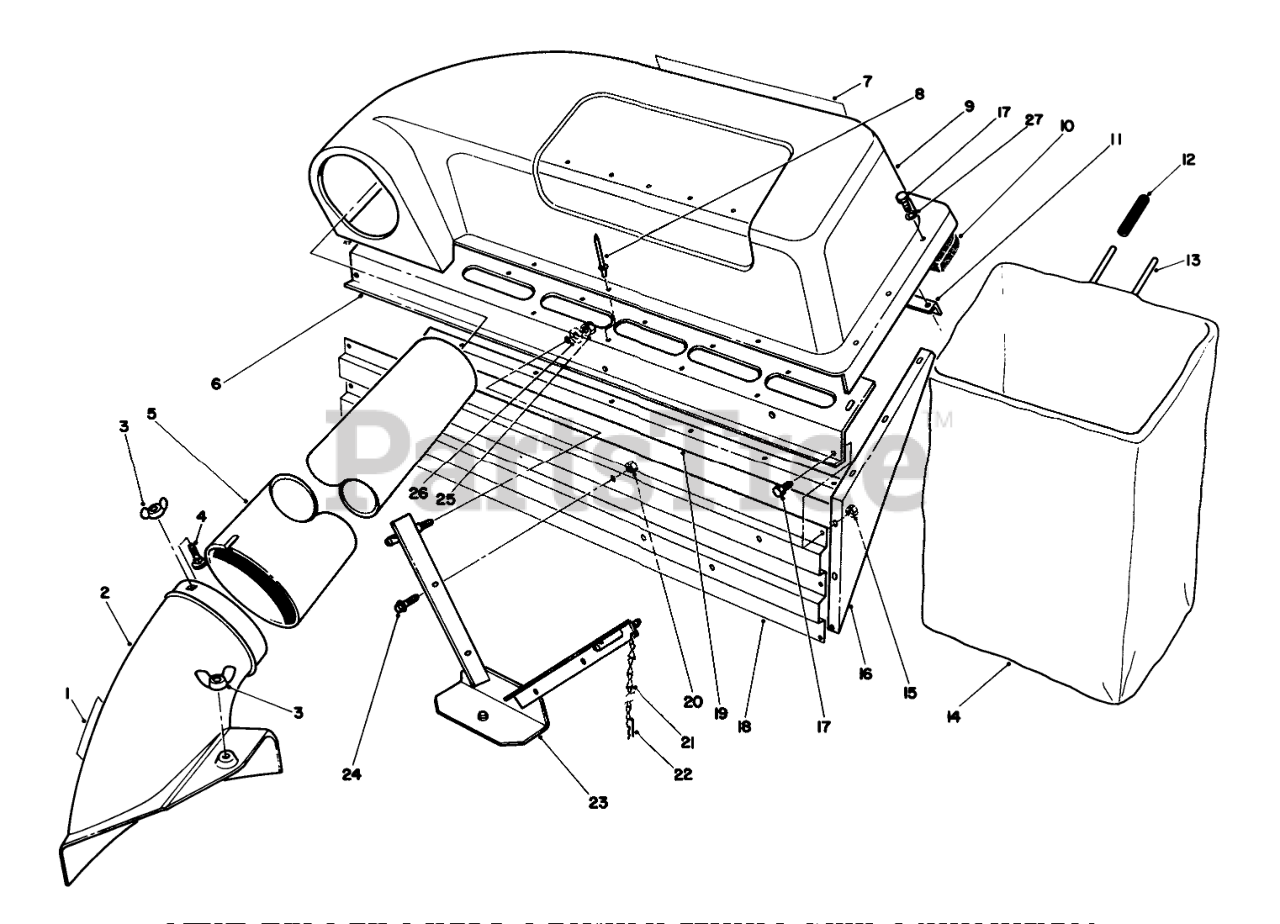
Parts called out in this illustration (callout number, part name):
1	DECAL-DANGER
2	Chute
3	NUT-WING SPECL
4	BOLT-CARR
6	COVER SUPT BAFFLE B
7	Decal-Twin Bagger
8	RIVET-POP
9	COVER
10	FOAM SEAL
11	BAG FRAME BRKT
12	GRIP-HANDLE, BAG
13	BAG FRAME
15	NUT-LOCK, NI
16	Plate-Side
17	SCREW-HH
18	MUFFLER SHIELD
19	BAG SUPPORT CHANNEL
20	NUT-LOCK, NI
21	6-LINK CHAIN W/HOOK
22	PIN-HAIR
23	V-Bracket
24	SCREW-HH
25	NUT-LOCK, NI
26	WASHER-FLAT
27	WASHER-FLAT
